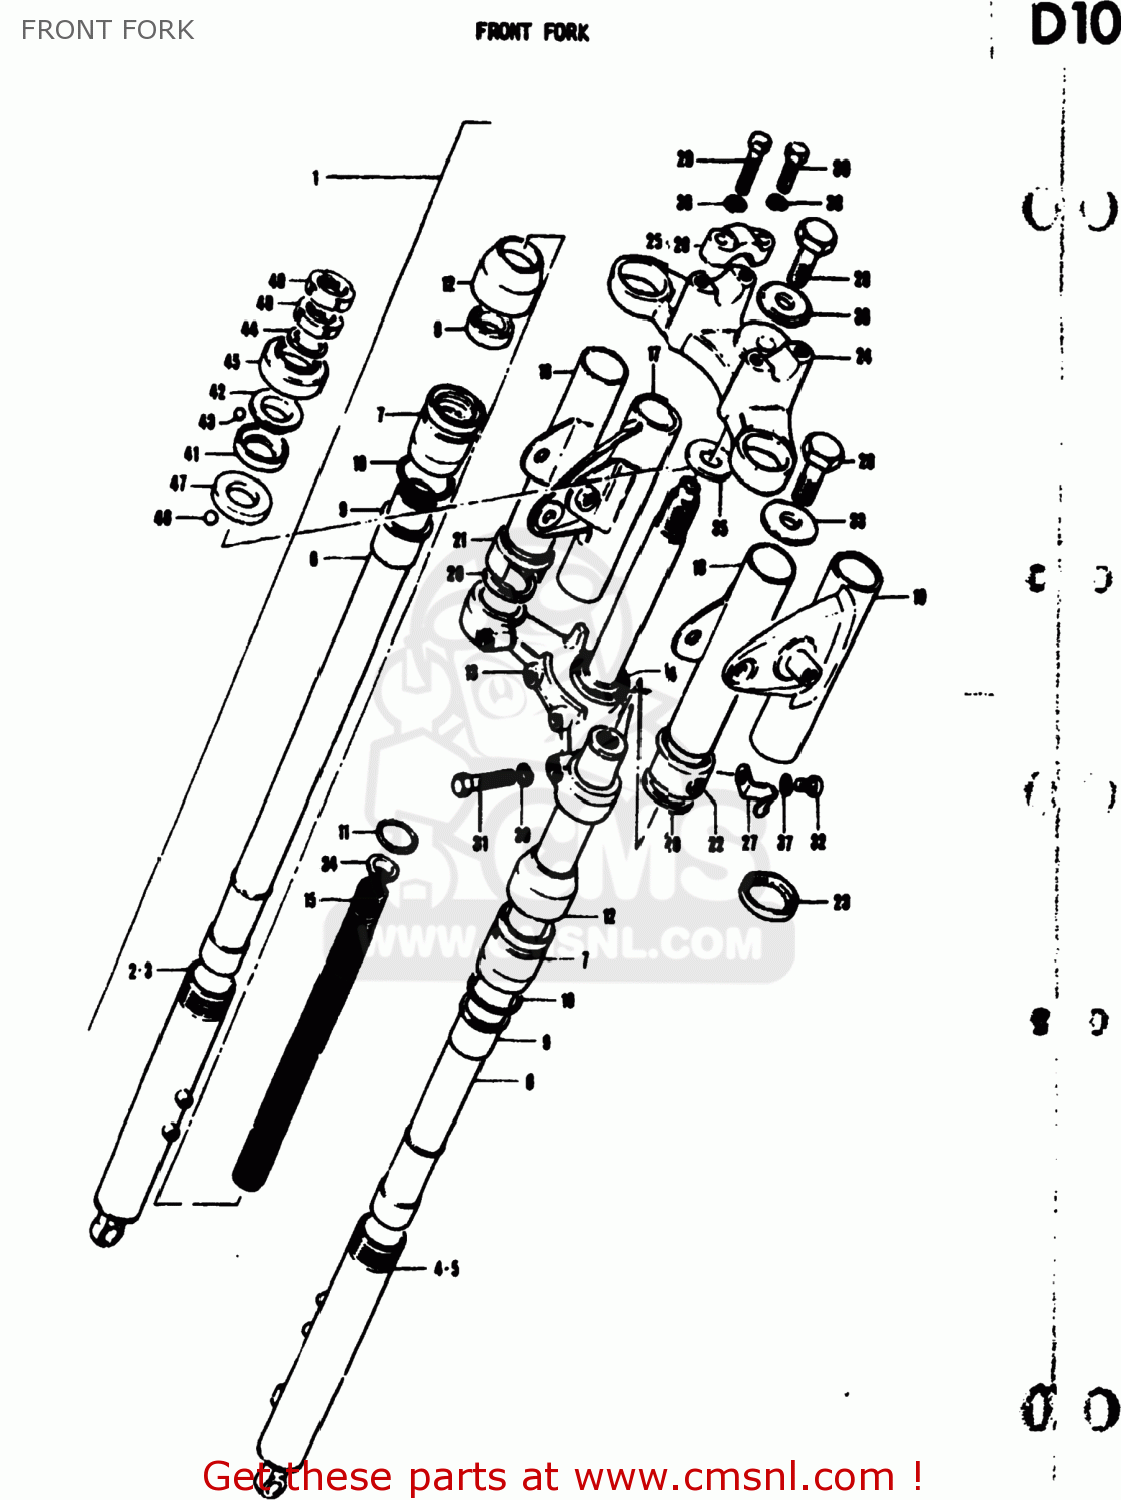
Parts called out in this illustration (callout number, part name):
1	DAMPER SET
2	TUBE,OUTER
3	TUBE,OUTER,LEFT
4	CYLINDER,FRONT FORK
5	SCREW
6	GASKET
7	TUBE,FORK,INNER
8	OIL SEAL,FRONT FORK
9	GUIDE,FRONT FORK TUBE
10	O-RING,FORK INNER TUBE
11	SEAL,DUST
12	BAND,FRONT FORK COVER
13	STEM,STEERING
14	RACE,STEERING OUTER LWR
15	SPRING
16	GUIDE,FRONT FORK SPRING C
17	SPACER,SPRING
18	BRACKET COMP,HEADLAMP
19	BRACKET,HEADLAMP,LEFT
20	CUSHION,HEADLAMP BRACKET
21	SCREW
22	GASKET,DRAIN,PLUG (NAS)
23	COVER STEM RH
24	COVER STEM LH
25	HEAD,STEERING STEM
26	BOLT,FORK INNER TUBE
27	WASHER
28	WASHER
29	HOLDER,HANDLEBAR
30	Bolt
32	LOCK WASHER
33	BOLT,FORK INNER TUBE F
34	LOCK WASHER
35	CIRCLIP
36	RING,FORK BACK UP
37	WASHER,STEERING STEM L
38	CLIP,BRAKE CABLE
39	SCREW
40	LOCK WASHER
